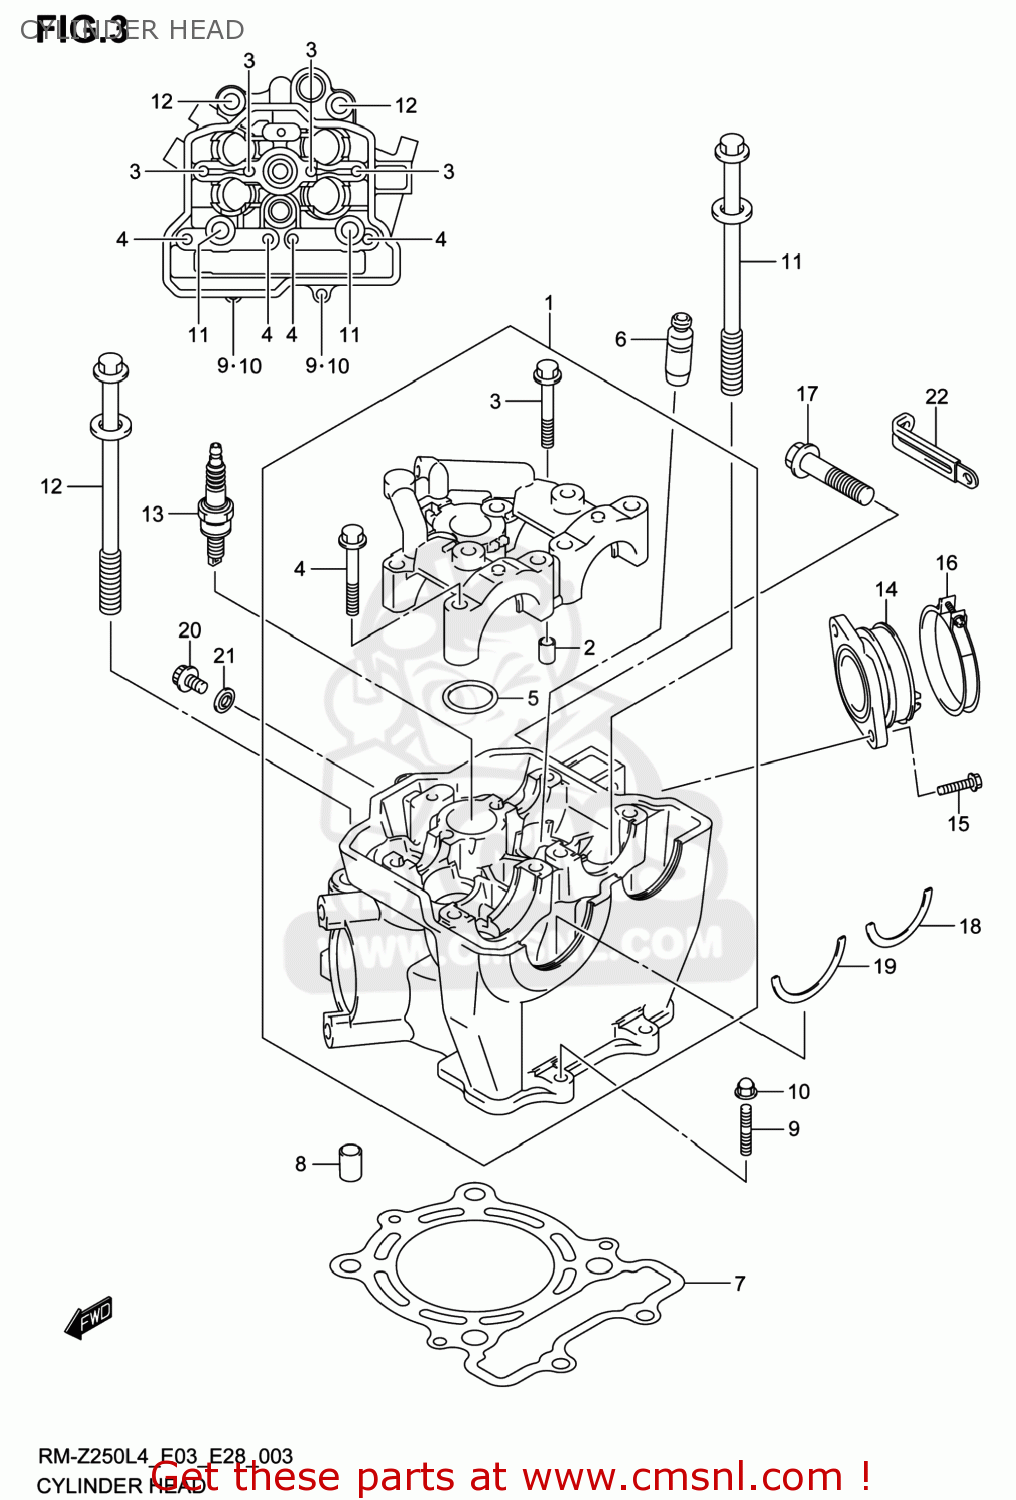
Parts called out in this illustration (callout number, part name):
1	HEAD ASSY,CYLINDER
2	PIN(6.2X8X11)
3	BOLT(6X40)
4	BOLT(6X45)
5	O RING(D:2.4,ID:25.7)
6	GUIDE,VALVE(OS:0.3)
7	GASKET,CYLINDER HEAD (NAS)
8	PIN
9	BOLT,STUD
10	NUT
11	BOLT,CYLINDER HEAD
12	BOLT,CYLINDER HEAD
13	PLUG,SPARK(CR8EIB-10)
14	PIPE ASSY,INTAKE
15	BOLT
16	CLAMP,INTAKE PIPE
17	BOLT(10X40)
18	C RING,CAMSHAFT
19	C RING,CAMSHAFT
20	BOLT
21	GASKET(5.8X13X1.2) (NAS)
22	CLAMP(L:45)
